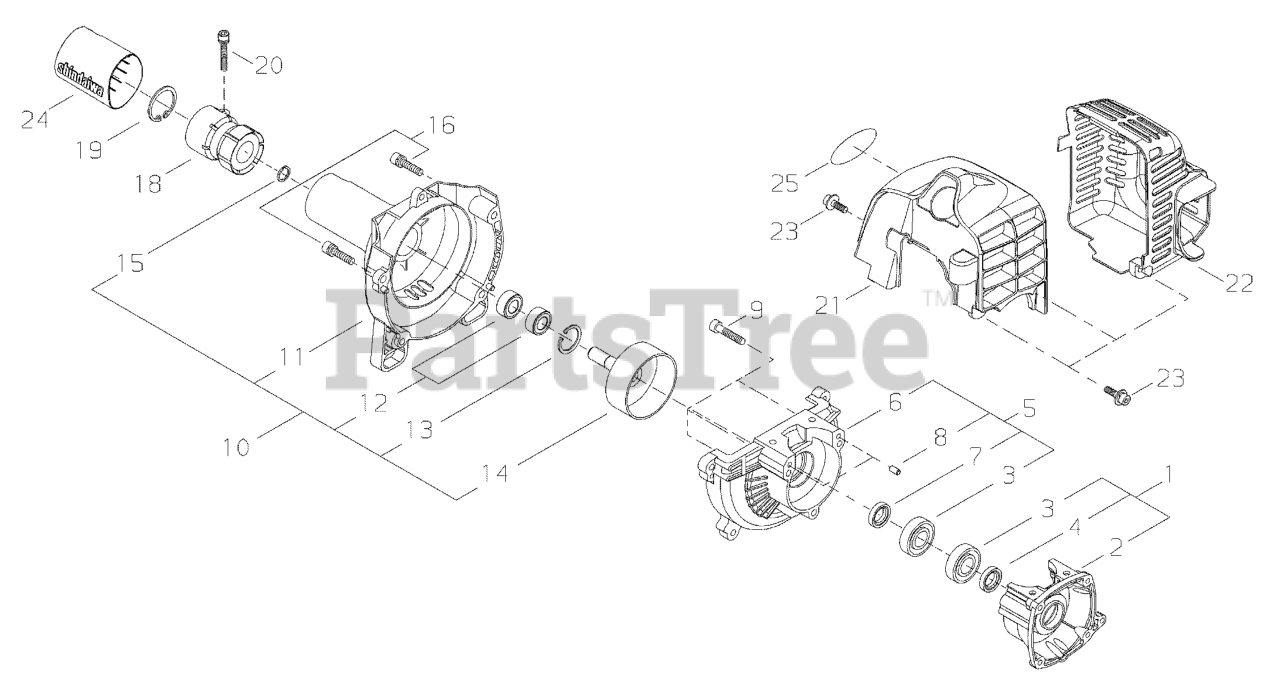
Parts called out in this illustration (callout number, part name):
1	CRANKCASE ASSY - REAR
2	CRANKCASE - REAR
3	BEARING, BALL - 6001C3
4	SEAL, OIL - 12
5	CRANKCASE ASSY - FRONT
6	CRANKCASE - FRONT
7	SEAL, OIL - 12
8	PIN - LOCATING
9	SCREW - 5X25
10	FAN CASE ASSY
11	CASE, FAN
12	BEARING, BALL - 6000
13	RING, RETAINING - 26
14	DRUM, CLUTCH
15	RING, RETAINING
16	SCREW - 5X18
18	CUSHION
19	RING, RETAINING - 40
20	SCREW - 5X22
21	COVER, ENGINE
22	COVER, EXHAUST
23	SCREW - 4X16
24	PROTECTOR
25	LABEL - MODEL 242
